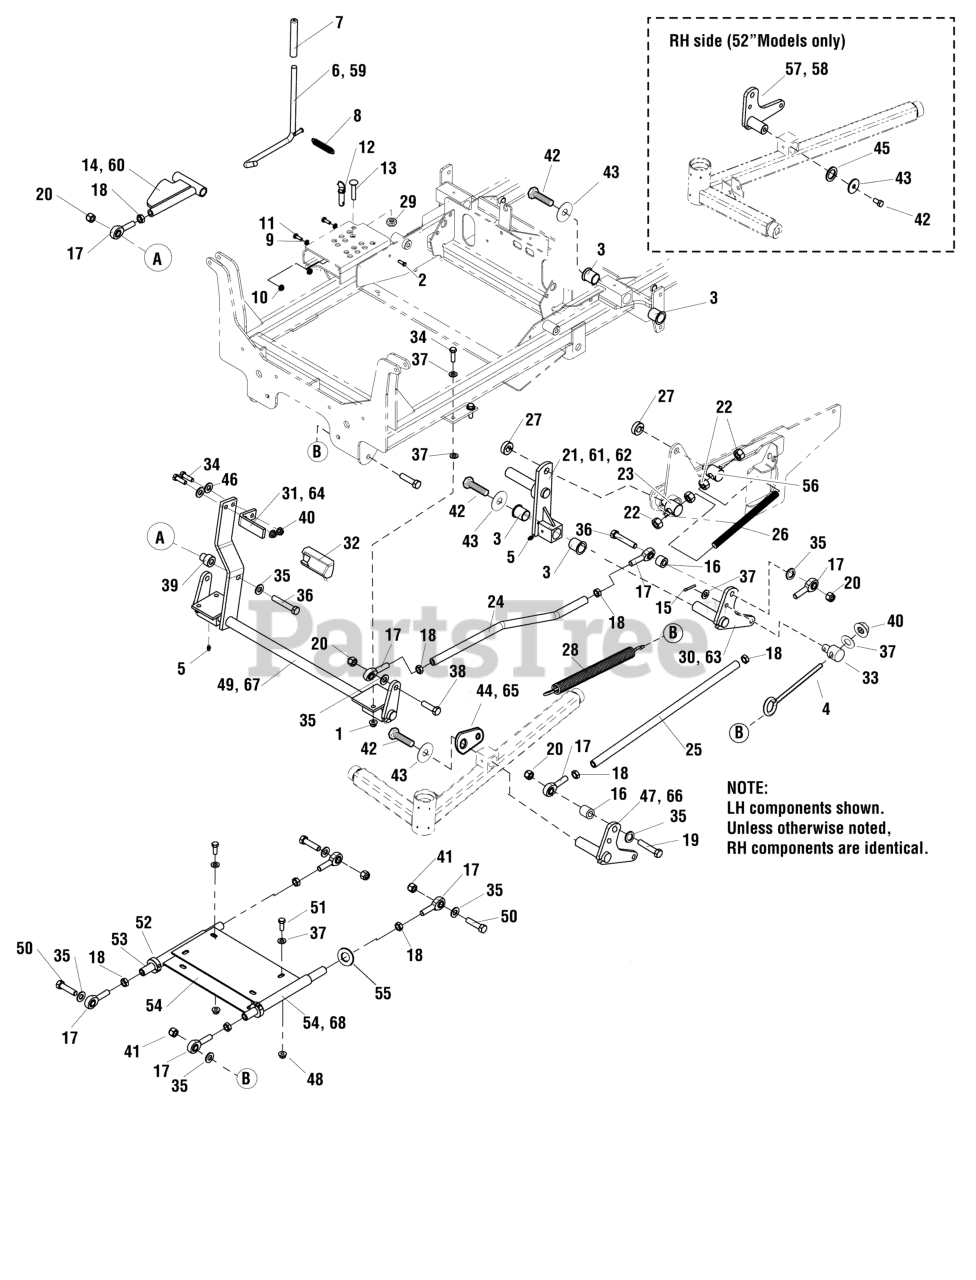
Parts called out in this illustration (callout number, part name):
1	NUT, 3/8-16 HEX NYLOCK FLANGE
2	PIN, CLEVIS, 1/4 X 7/8, PLATED
3	BUSHING, 1.00 X 1.13 X 1.38, PLASTIC
4	EYE BOLT, 3/8-16 X 8", 1" EYE
5	GREASE FITTING, 1/4-28 STRAIGHT
6	WELD, ROD DECK LIFT - BLK
7	GRIP, FOAM
8	SPRING, EXTENSION
9	WASHER, 1/4 SAE
10	NUT, 1/4-20 HEX SERR. FLANGE
11	BOLT, 1/4-20 X 3/4" GD5 YZ
12	PIN, HITCH, 1/2 X 2.00 OAL, YP
13	BOLT, 3/8-16 X 2", CARRIAGE
14	WELD, DECK ADJUST LINK - RED MODEL
15	PIN, COTTER, 1/8" X 3/4
16	SPACER, .52 X 1.00 X .75
17	BALL JOINT, 1/2-20, MALE
18	NUT, 1/2-20 HEX JAM
19	BOLT, 1/2-13 X 2-3/4 GD5 CZ
20	NUT, 1/2-13 HEX NYLON LOCK
21	WELD, REAR LIFT, LH - BLK
21	WELD, REAR LIFT, RH - BLK
22	NUT, 5/8-11 HEX
23	PIVOT, SPRING ROD
24	ROD, DECK LIFT BENT
25	ROD, DECK LIFT OUTER
26	ROD, 5/8-11 X 9.00
27	COLLAR, 5/8" SPLIT
28	SPRING, DECK LIFT ASSIST
29	NUT, 3/8-16 HEX SIDE LOCK
30	WELD, DECK LIFT LEVER, LH - BLK
31	PEDAL, FOOT - BLK
32	PEDAL, Rubber
33	ADJUSTER, DECK HANGER
34	BOLT, 3/8-16 X 1-1/4" GD5 CZ
35	WASHER, 1/2" GD9 YZ
36	BOLT, 1/2-13 X 3-1/2, HEX HD, GD5, CZ (SV)
37	WASHER, 3/8 SAE
38	BOLT, 1/2-13 X 1-3/4 GD5 CZ
39	ADAPTER, CASTER AXLE, CZ
40	NUT, 3/8-16 HEX NYLON LOCK
41	NUT, Hex, Nylon Lock, 1/2-20
42	BOLT, 3/8-16 X 3/4, PLT W/PATCH
43	WASHER, .390 X 1.50 X .109, YZ
44	MOUNT, SPRING, DECK LIFT - RED MODEL
45	SHIM, 1.0 X 1.5 X 0.125
46	WASHER, 3/8" GR9 FLAT
47	WELD, DECK LIFT LEVER, LH - RED MODEL
48	NUT, 3/8-16 HEX SERRATED FLANGE
49	WELD, DECK LIFT SHAFT - RED MODEL
50	BOLT, 1/2-20 X 1-3/4" GD8 CZ
51	BOLT, 3/8-16 X 1" GD5 CZ
52	COLLAR, 3/4" SPLIT
53	SHAFT, DECK STABILIZER
54	WELD, DECK STABILIZER - BLK
55	WASHER, 1/2 SAE
56	PIVOT, SPRING ROD
57	WELD, DECK LIFT LEVER, RH - RED MODEL
58	WELD, DECK LIFT LEVER, RH - ORANGE MODEL
59	WELD, ROD DECK LIFT - BLK
60	WELD, DECK ADJUST LINK - ORANGE MODEL
61	WELD, REAR LIFT, LH - BLK
62	WELD, REAR LIFT, RH - BLK
63	WELD, DECK LIFT LEVER, LH - BLK
64	PEDAL, FOOT - BLK
65	MOUNT, SPRING, DECK LIFT - ORANGE MODEL
66	WELD, DECK LIFT LEVER, LH - ORANGE MODEL
67	WELD, DECK LIFT SHAFT - ORANGE MODEL
68	WELD, DECK STABILIZER - BLK
